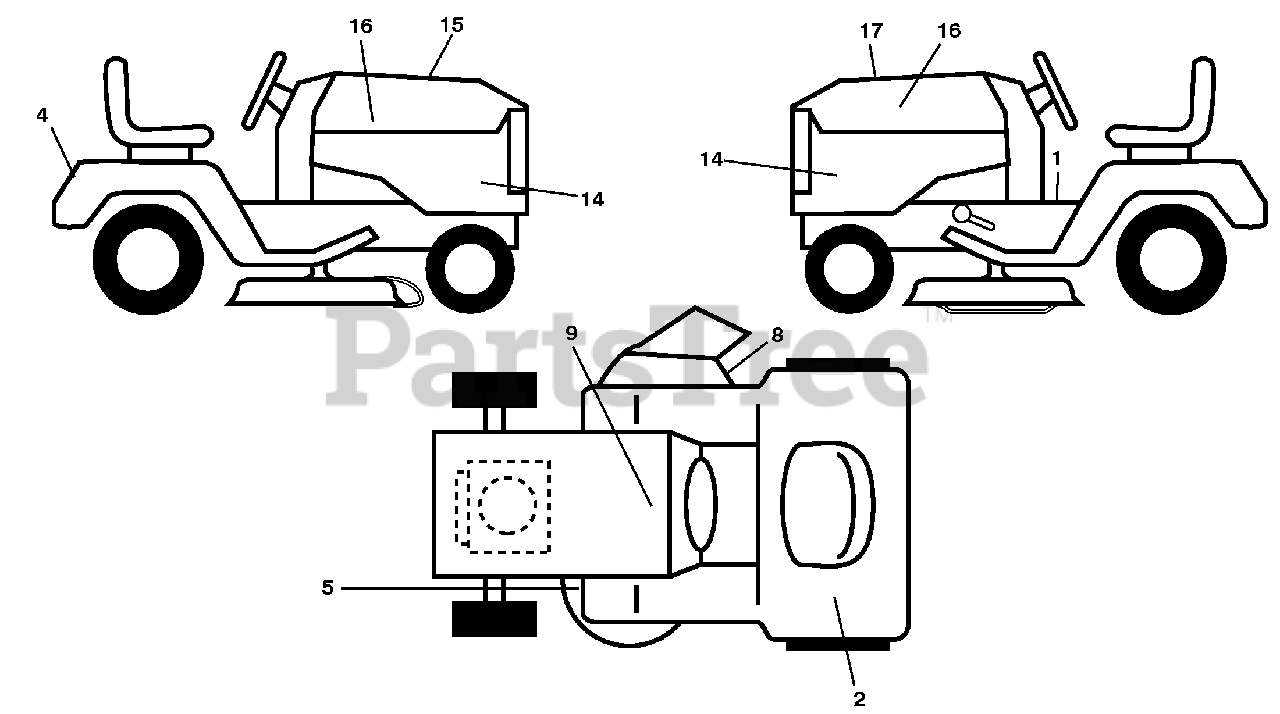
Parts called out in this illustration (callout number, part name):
1	Decal, Warning
2	Decal, Ethanol E85
4	Decal, Fender
5	Decal, Caution
8	Decal, Mower Sch.
9	Decal, Battery Dnge/Poi
14	Decal, Panel Side
15	Decal, Warning Customer Resp.
16	Decal, Hood Logo
17	Decal, Replacement
18	Decal, Bypass
19	Pad, Footrest, LH
20	Pad, Footrest, RH
